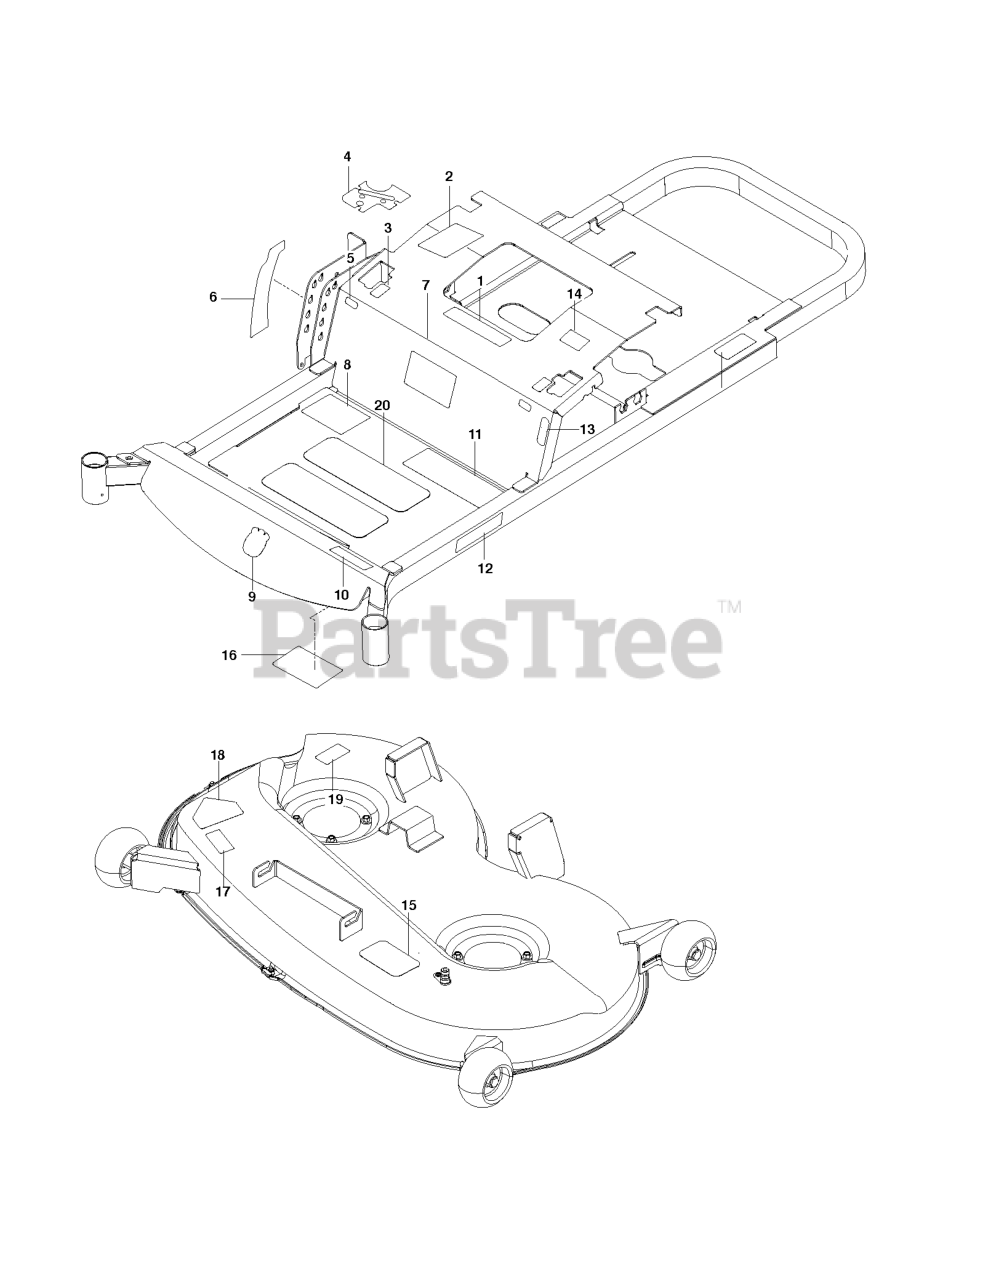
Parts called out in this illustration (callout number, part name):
1	EURO DECAL-BATTERY WARNIN6
2	DECAL, CUSTOMER RESPNSIBILITY
3	DECAL, MOTION CONTROL
4	DECAL, CTRL PANEL HUS WO CHOKE
5	DECAL, F.S.T.
6	DECAL, HEIGHT
7	DECAL, START
8	DECAL, WARNING
9	DECAL.AUGER.HUSQ.CROWN.SNOW
10	DECAL, RZ4621 (BF UNIT)
11	DECAL, SAFETY WARNING
12	RP.DECAL.BADGE.170MM.TEXTLOGO
13	DECAL, PARK BRAKE
14	DECAL, EXITING MOWER
15	DECAL, BELT ROUTING
16	DECAL, SERVICE
17	DECAL, EURO SEVERING
18	DECAL, CPSC
19	DECAL, CAUTION
20	DECAL, DO NOT TOW
21	ANTI-SKID PAD
